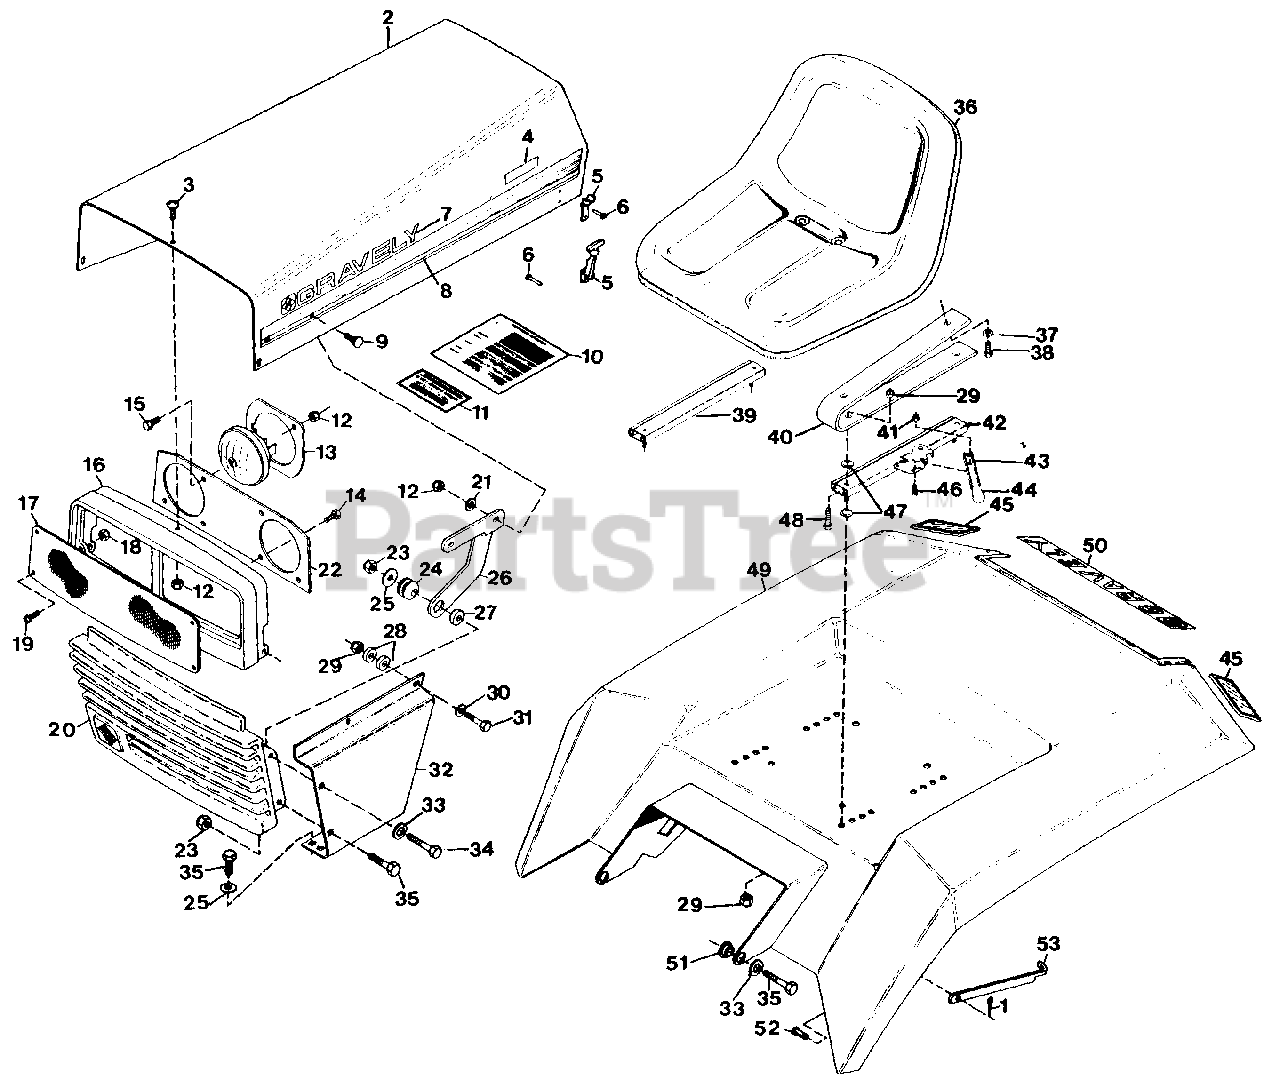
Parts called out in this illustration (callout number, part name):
1	PIN, COTTER .06X.75
2	HOOD, SILK SCREEN
3	SCREW, MACHINE 1/4-20 PHD
4	DECAL, MODEL 24-G
5	LATCH, FLEXIBLE
6	RIVET, DOME HEAD
7	DECAL, GRAVELY LOGO
8	DECAL, SIDE STRIPE L.H. AND R.H.
9	BOLT, 1/4-20X.75 RD HD SQ NK
10	DECAL, MAINTENANCE
11	DECAL, ELECTRICAL SYSTEM WARNING
12	NUT, LOCK 1/4-20
13	RING, HEADLIGHT RETAINER
14	SCREW, 1/4-20X.50 SELF-TAPPING
15	BOLT, HEX 1/4-20X1.00
16	BEZEL, HEADLIGHT
17	PANEL, HEADLIGHT LENSE
18	NUT, LOCK 10-24
19	SCREW, MACHINE 10-24X.75 PHD
20	CASTING, GRILLE
21	WASHER, FLAT .281X.625X.065
22	PANEL, HEADLIGHT REFLECTOR
23	NUT, LOCK 3/8-16
24	GROMMET
25	WASHER, FLAT .438X1.000X.083
26	HINGE, HOOD L.H.
26	HINGE, HOOD R.H.
27	SPACER
28	SPACER, .375X.100X1.00
29	NUT, LOCK 5/16-18
30	WASHER, FLAT .344X.688X.065
31	BOLT, HEX 5/16-18X1.75
32	PANEL, SIDE L.H.
32	PANEL, SIDE R.H.
33	WASHER, FLAT .406X.812X.065
34	BOLT, HEX 3/8-16X2.00
35	BOLT, HEX 3/8-16X1.00
36	SEAT, HIGH BACK
37	WASHER, LOCK 5/16 REG.
38	BOLT, HEX 5/16-18X.75
39	ADJUSTER, SEAT
40	SPRING, SEAT
41	NUT, LOCK 10-24
42	ADJUSTER, SEAT W/LATCH
43	HANDLE, SEAT SLIDE
44	TIP, LEVER
45	REFLECTOR, RED SAFETY
46	SCREW, MACHINE 10-I4X.625 PHD
47	SPACER
48	BOLT, HEX 5/16-18X1.25
49	WELDMENT, SEAT PAN NOTCHED
50	DECAL, GRAVELY LOGO
51	BUSHING, REAR FENDER
52	PIN, CLEVIS .250X.406
53	STRAP, FENDER HOLD-UP
